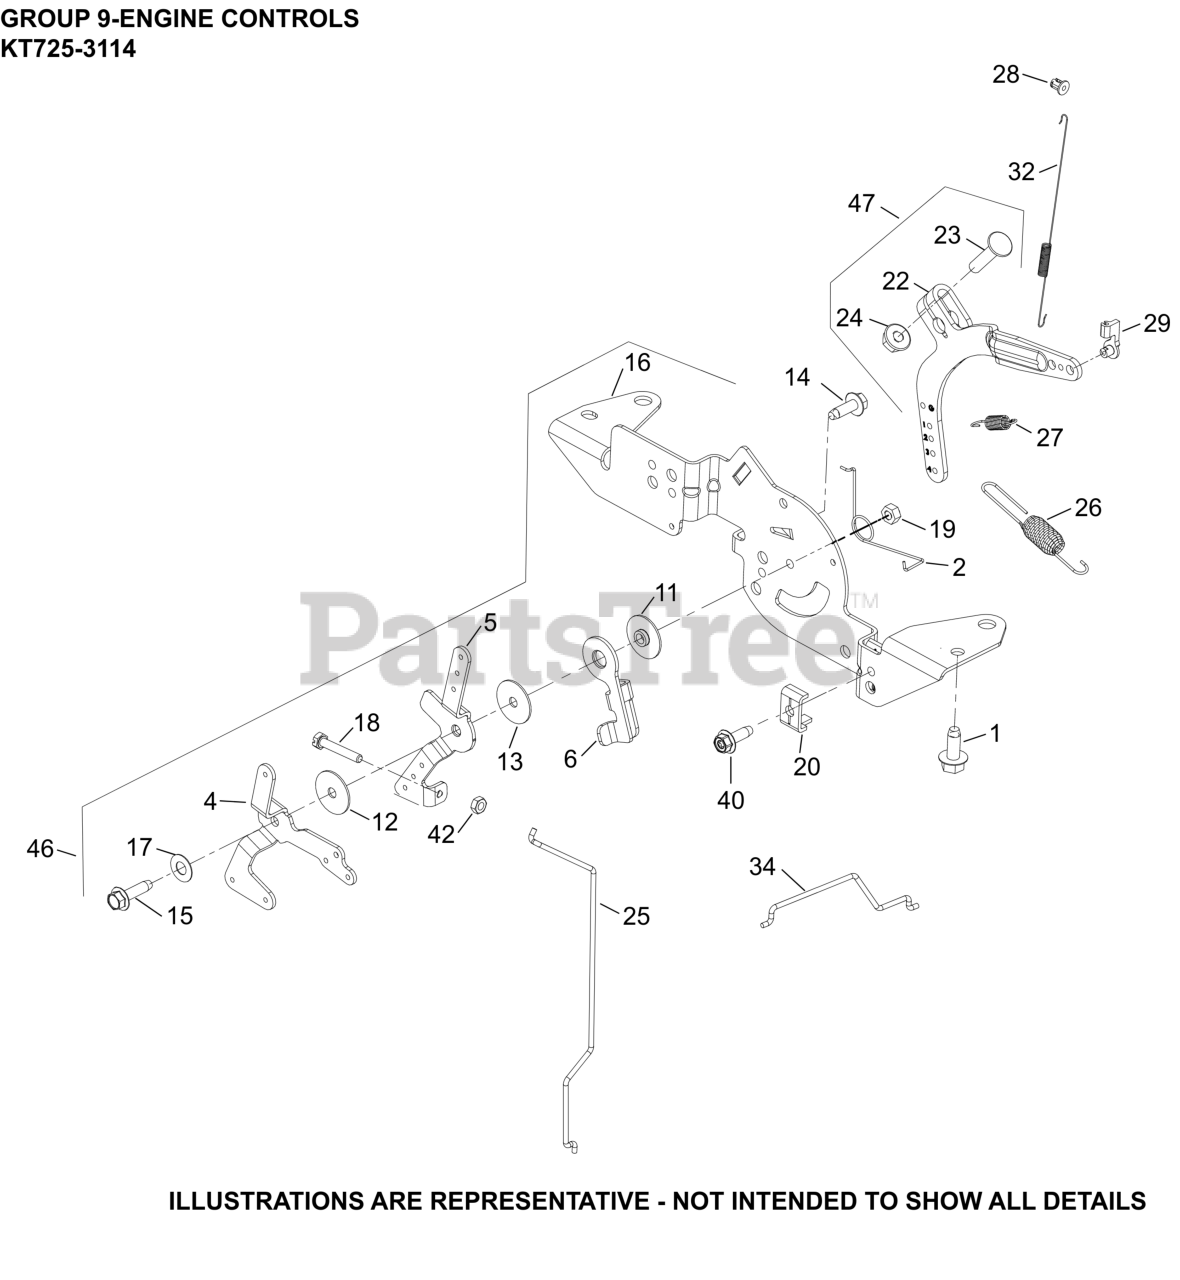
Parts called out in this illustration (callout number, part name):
1	SCREW, THREAD FORMING
2	SPRING, CHOKE RETURN
4	LEVER, CHOKE
5	LEVER, THROTTLE CONTROL
6	LEVER, THROTTLE ACTUATOR
11	SPACER, CONTROL ASSEMBLY
12	WASHER, FLAT 5.5 MM
13	WASHER, FLAT 5 MM
14	SCREW, THREAD FORMING
15	SCREW, THD FRM-USE 25 086 473-S
16	BRACKET, SPEED CONTROL
17	WASHER, SPRING 1/4"
18	SCREW, SLT HD CAP M4X0.7X25
19	NUT, LOCK M5X.8
20	CLAMP, CABLE CABLE
22	LEVER, GOVERNOR - (#2409069S)
23	BOLT, RD HD SQ NECK M6X1.0X25
24	NUT, FLG M6X1.0
25	LINKAGE, CHOKE
26	SPRING, GOVERNOR
27	SPRING, GOVERNED IDLE
28	BUSHING, LINKAGE RETAINING
29	BUSHING, THROTTLE LINKAGE
32	SPRING, LINKAGE
34	LINKAGE, THROTTLE
40	SCREW, THREAD FORMING
42	NUT, M4X0.7
46	CONTROL ASSEMBLY, DUAL WIRE
47	LEVER, GOVERNOR ASSEMBLY
